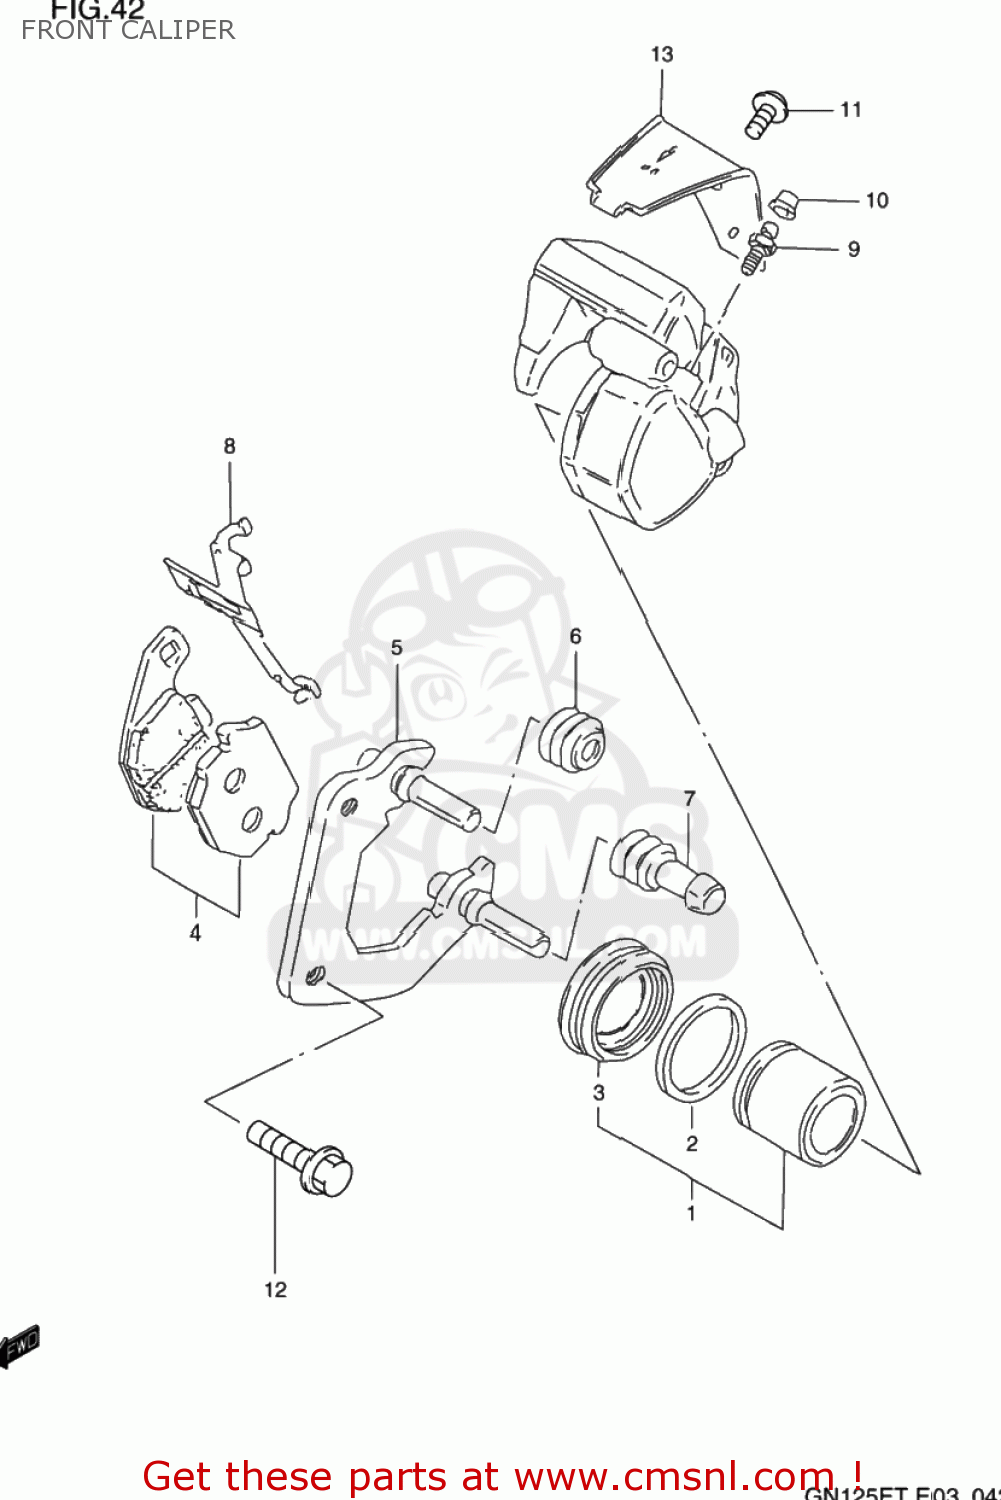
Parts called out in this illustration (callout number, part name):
1	PISTON SET
2	SEAL,PISTON
3	BOOT,PISTON
4	PAD SET (NAS)
5	CARRIER,L
6	BOOT,AXLE
7	INSULATOR,AXLE
8	SPRING,PAD
9	BLEEDER
10	CAP,BLEEDER PLUG
11	SCREW
12	BOLT
13	PROTECTOR,CALIPER
